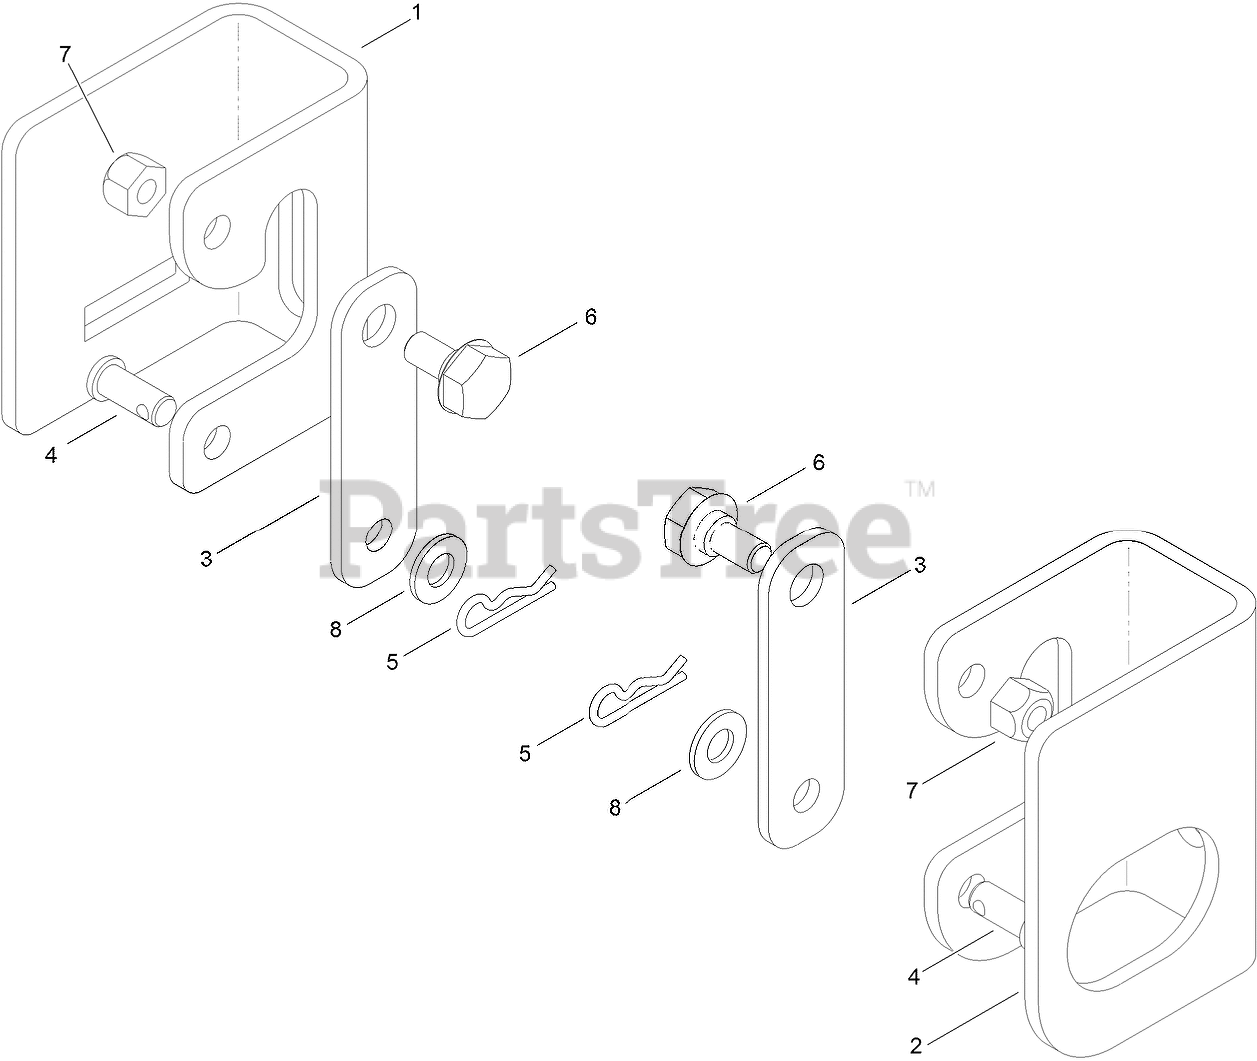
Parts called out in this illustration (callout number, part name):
1	BRACKET-HANGER, RH
2	BRACKET-HANGER, LH
3	BRACKET-DECK SUPPORT
4	PIN-CLEVIS
5	PIN-COTTER
6	BOLT-SHOULDER
7	NUT-LOCK, NI
8	WASHER-PLAIN
